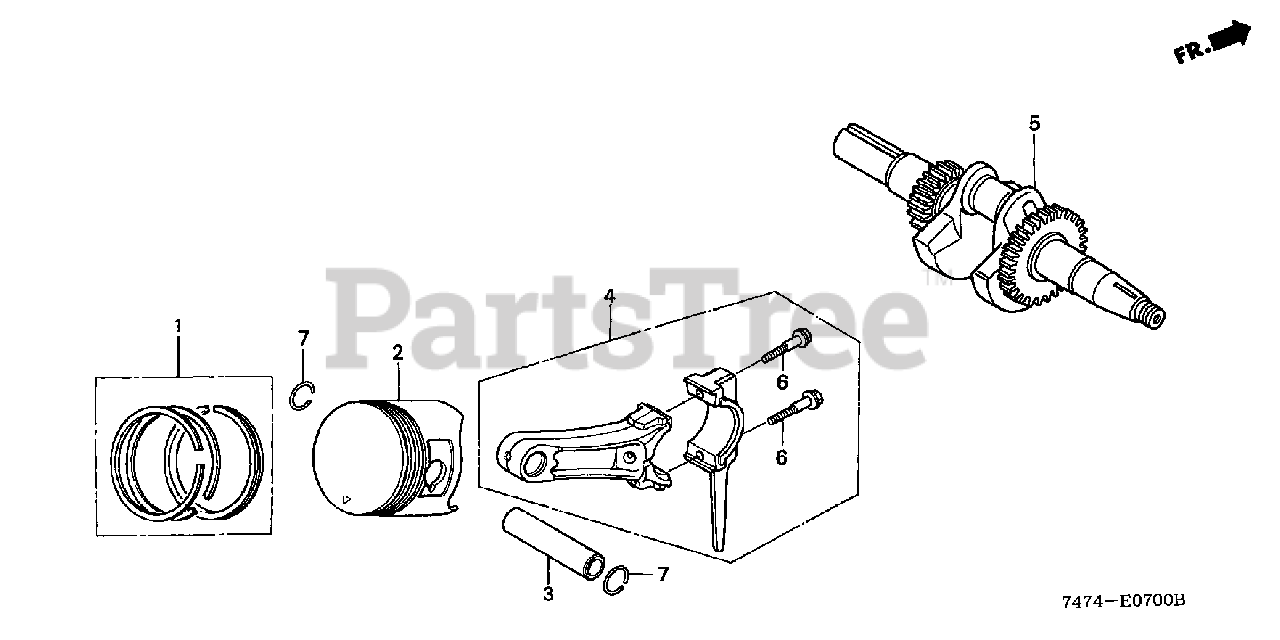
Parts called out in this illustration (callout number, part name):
1	RING SET, PISTON (STD)
1	RING SET, PISTON (OS 0.25)
1	RING SET, PISTON (OS 0.50)
1	RING SET, PISTON (0.75)
2	PISTON (STD)
2	PISTON (OS 0.25)
2	PISTON (OS 0.50)
2	PISTON (0.75)
3	PIN, PISTON
4	ROD ASSY., CONNECTING (US 0.25)
4	ROD ASSY., CONNECTING
5	CRANKSHAFT (S-TYPE)
6	BOLT, CONNECTING ROD
7	CLIP, PISTON PIN (18MM)
